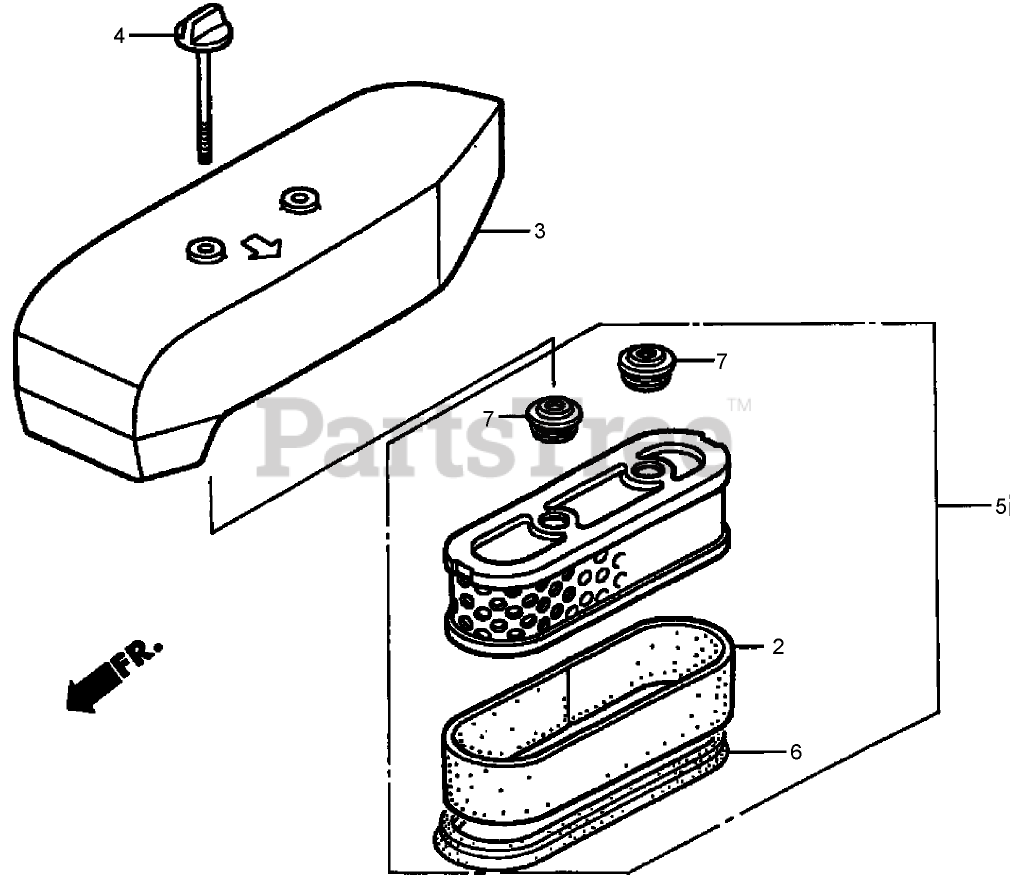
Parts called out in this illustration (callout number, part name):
2	Filter (Outer)
3	COVER-CLEANER, AIR
4	BOLT-CLEANER, AIR (6X73)
5	ELEMENT-CLEANER, AIR
6	Gasket-Element
7	GROMMET-CLEANER, AIR
